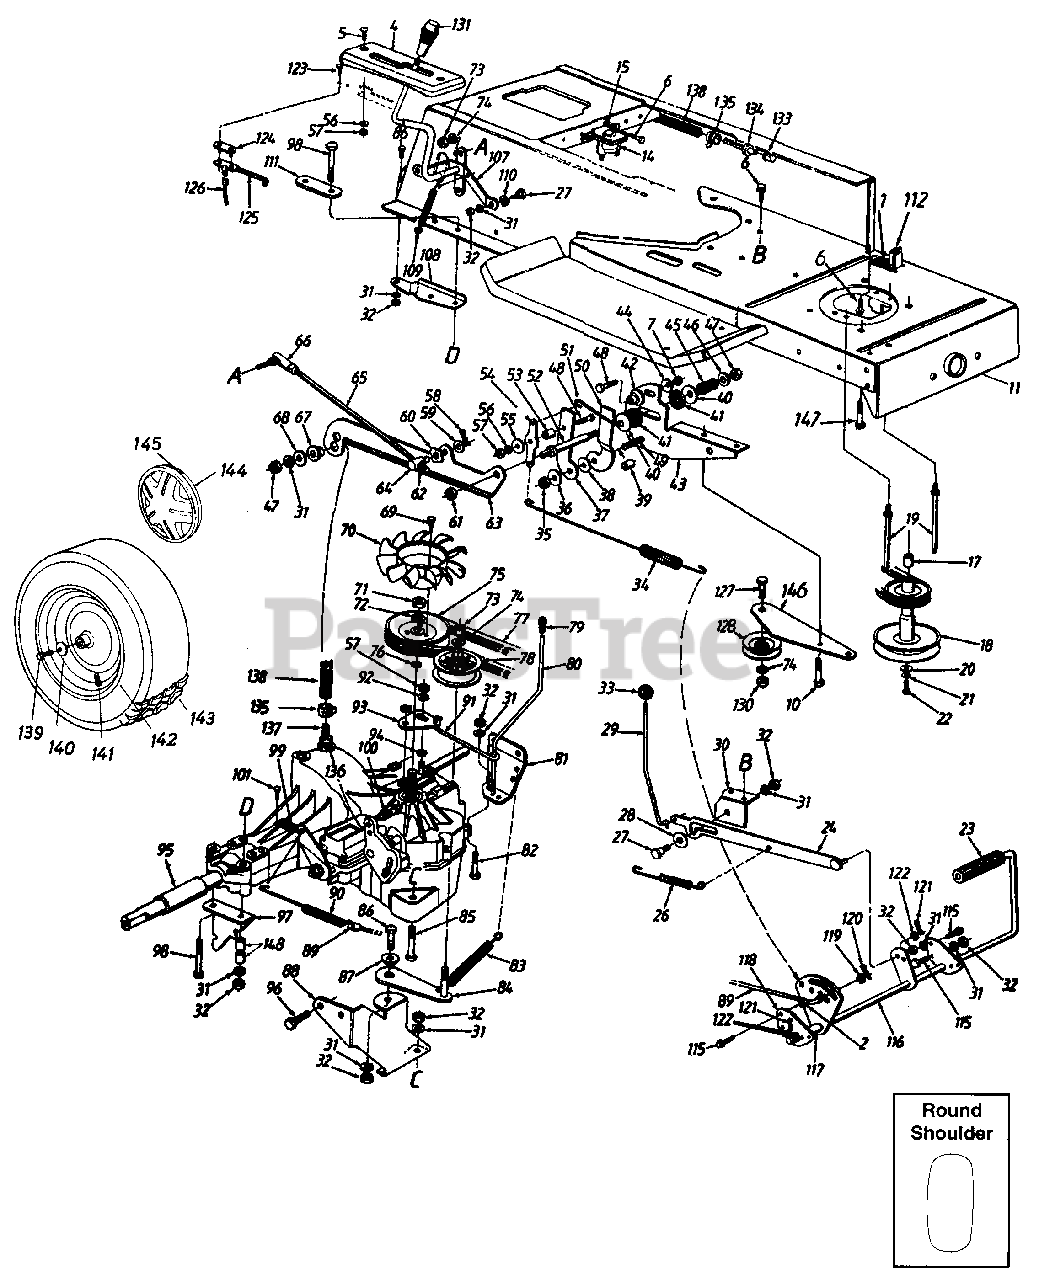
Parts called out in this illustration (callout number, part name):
1	Spring Switch
2	Hex Sems Nut 5/16-18 Thd.
4	Index Bracket
5	Pan Hd. Mach. Scr. 1/4-20 x .75" Lg.
6	Hex Wash. Hd. TT-Tap Scr. 1/4-20 x .5" Lg.
7	Hex Nut 1/4-28 Thd.
10	Hex . Bolt 1/4-28 x .62" Lg.
14	Solenoid
15	Ext. L-Wash. 1/4" I.D.
18	Engine Pulley
19	Belt Guard Stud 4.75" Lg.
20	Fl-Wash. 7/16" I.D. x 1.25" O.D.
21	L-Wash. 7/16" I.D.
22	Hex Bolt 7/16-20 x 1.5" Lg.
23	Foot Pad
27	Shld. Bolt .437" Dia. x .268"
28	Fl-Wash. 7/16" I.D. x 1-3/8" O.D.
29	Lock-up Rod
31	L-Wash. 5/16" I.D.
32	Hex Nut 5/16-18 Thd.
34	Neutral Return Spring
35	Hex Nut 5/16-24 Thd.
36	Fl-Wash. .344" I.D. x 1" O.D.
37	Scissor-Flat
38	Fl-Wash. .33" I.D. x 1.25" O.D.
40	Bell-Wash. .4" I.D. x 1.13" O.D.
41	Friction Washer
42	Centering Gauge Spacer
43	Neutral Return Mtg. Brkt.
44	Bell-Wash. .265" I.D. x .75" O.D.
45	Comp. Spring 1.19" Lg.
46	Fl-Wash. .26" I.D. x .72" O.D.
47	Hex Nut 5/16-24 Thd.
48	Hex Bolt 1/4-28 x 1" Lg. (Gr. 5)
49	Rib Neck Bolt 5/16-24 x .84" Lg.
50	Scissor-Offset
51	Neutral Return Rod
52	Friction Disc Stud
53	Shld. Spacer
54	Neutral Return Lever
55	Fl-Wash. .265" I.D. x 1" O.D.
56	L-Wash. 1/4" I.D.
57	Hex Nut 1/4-20 Thd.
58	Hairpin Clip
59	Fl-Wash. .375" I.D. x .87" O.D.
60	Spring Wash. .39" I.D.
61	Hex L-Nut 3/8-24 Thd.
62	Hex Jam Nut 3/8-24 Thd.
63	Neutral Return Brkt.
64	Ferrule 3/8-24 Thd.
65	Control Rod
66	Ball Joint 3/8-24 Thd.
67	Shld. Spacer .5" Dia. x .27" Lg.
68	Fl-Wash. .349" I.D. x .879" O.D.
69	Hex Tap Scr. #12 x 3/8" Lg.
70	Fan
71	Hex Nut 1/2-20 Thd.
72	L-Wash. 1/2" I.D.
73	Hex Nut 3/8-24 Thd.
74	L-Wash. 3/8" I.D.
75	Transmission Pulley
78	Fl-Idler Pulley 2.75" O.D.
79	Rod End Grip
80	Bypass Control Lever
83	Ext. Spring 6.12
86	Hex Bolt 5/16-18 x .75" Lg.
87	Shld. Spacer .5" Dia. x .27" Lg.
90	Ext. Spring
91	Bypass Actuator Rod
92	Fl-Wash. .281" I.D. x .5" O.D.
93	Bypass Adjustment Brkt.
94	External L-Wash. 1/4" I.D.
95	Sleeve .758" I.D. x 1" O.D.
96	Hex . TT-Tap Scr. 5/16-18 x .62"
99	Tension Spring
100	Hex Bolt 5/16-24 x 1" Lg. (Special)
101	Hex Wash. Hd. AB-Tap Scr. #10 x .5" Lg.
107	Speed Control Lever Ass'y.
110	Spr-Wash. .445" I.D. x .75" O.D.
112	Safety Switch (Clutch)
115	Hex TT-Tap Scr. 5/16-18 x .75"
120	Cotter Pin 3/32" Dia.
121	Cotter Pin 1/8" Dia.
122	Fl-Wash. .385" I.D. x .62" O.D.
123	Hex AB-Tap Scr. #8 x .5" Lg.
124	Insulator Nut Plate
125	Reverse Safety Switch
126	Extension Wire
127	Hex Bolt 3/8-16 x 1.5" Lg.
128	Idler Pulley
130	Hex Nut 3/8-16 Thd.
134	Plastic Vent
135	Clamp
137	Hose Fitting
138	Fuel Line 20" Lg.
139	Hex Bolt 5/16-24 x .75" Lg.
140	Bell-Wash. .345" I.D. x .88" O.D.
141	Air Valve
148	Spacer .32" I.D. x .75" O.D.
